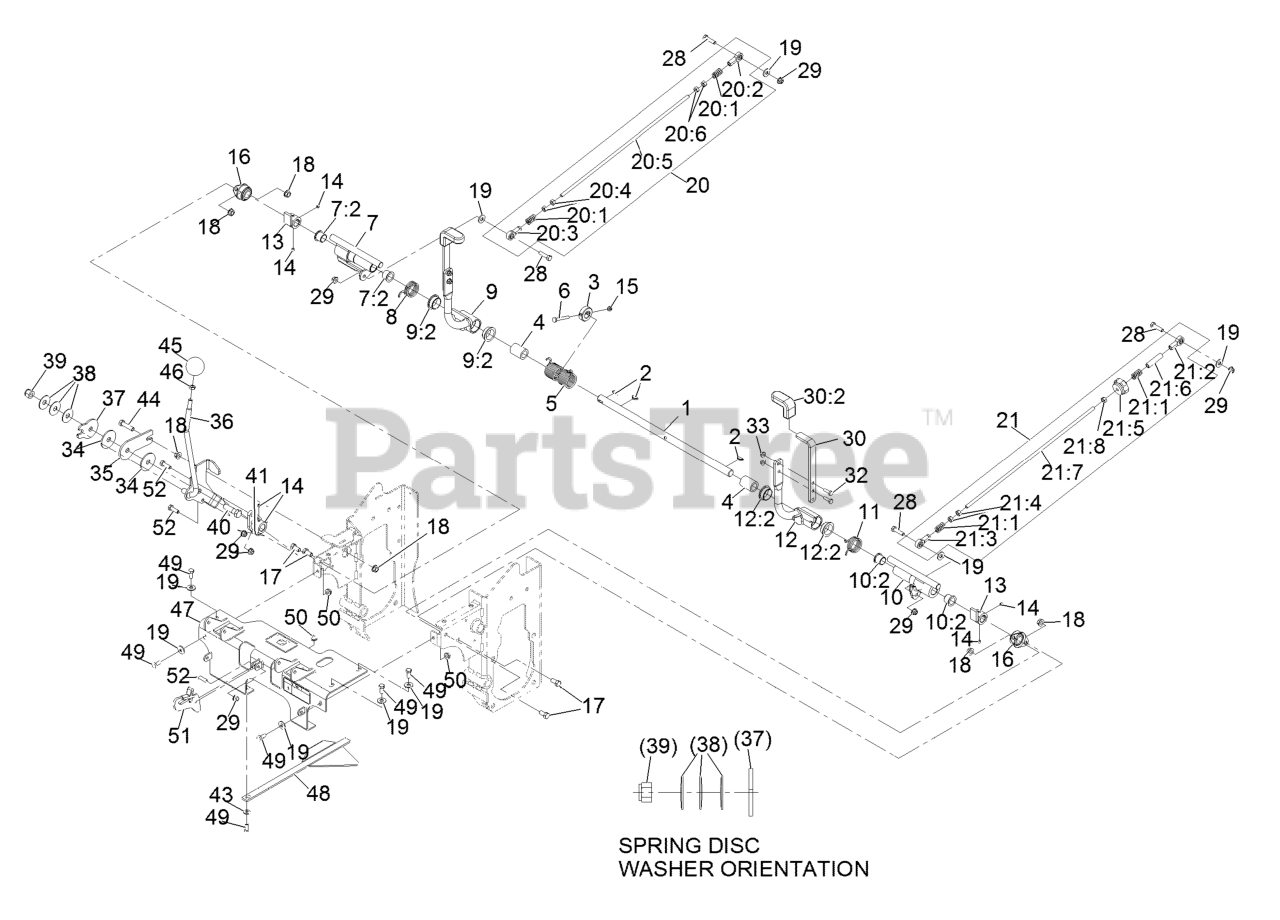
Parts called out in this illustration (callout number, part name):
1	SHAFT-CONTROL, SPEED
2	KEY-WOODRUFF
3	STOP-HUB, CENTER
4	BUSHING-PLASTIC
5	SPRING-TORSION, DOUBLE
6	SCREW-HH
7	RH CONTROL HUB ASM
7:2	BEARING-FLANGE, IGLIDE
8	SPRING-TORSION, RH
9	RH STEERING HANDLE ASM
9:2	BEARING-FLANGE, IGLIDE
10	LH CONTROL HUB ASM
10:2	BEARING-FLANGE, IGLIDE
11	SPRING-TORSION, LH
12	LH STEERING HANDLE ASM
12:2	BEARING-FLANGE, IGLIDE
13	HUB-SPEED CONTROL
14	SCREW-SET
15	NUT-LOCK, NI
16	BEARING-FLANGE, SIDE
17	SCREW-HH
18	NUT-HHF, WHIZ
19	WASHER-FLAT
20	RH PUMP LINKAGE ASM
20:1	SPRING-COMPRESSION
20:2	BALLJOINT-RH
20:3	BALLJOINT-LH
20:5	ROD-LINKAGE, STEERING
20:6	NUT-HEX
21	LH PUMP LINKAGE ASM
21:1	SPRING-COMPRESSION
21:2	BALLJOINT-RH
21:3	BALLJOINT-LH
21:5	KNOB-TRACKING
21:7	ROD-LINKAGE, STEERING
21:8	NUT-HEX
28	SCREW-HH
29	NUT-HF, NI
30	HANDLE ASM
30:2	GRIP-HANDLE, STEERING
32	SCREW-HH
34	DISC-FRICTION
35	PLATE-FRICTION, SPEED CON
36	LEVER-SPEED CONTROL
37	PLATE-FRICTION, SPEED CON
38	WASHER-DISC, SPRING
39	NUT-HEX
40	SCREW-HH
41	HUB-CONTROL, SPEED
43	WASHER-PLAIN
44	SCREW-HH
45	KNOB-BALL, SPEED CONTROL
46	NUT-JAM
47	CONSOLE ASM
48	GUIDE-PLENUM
49	SCREW-HH
52	SCREW-HH
